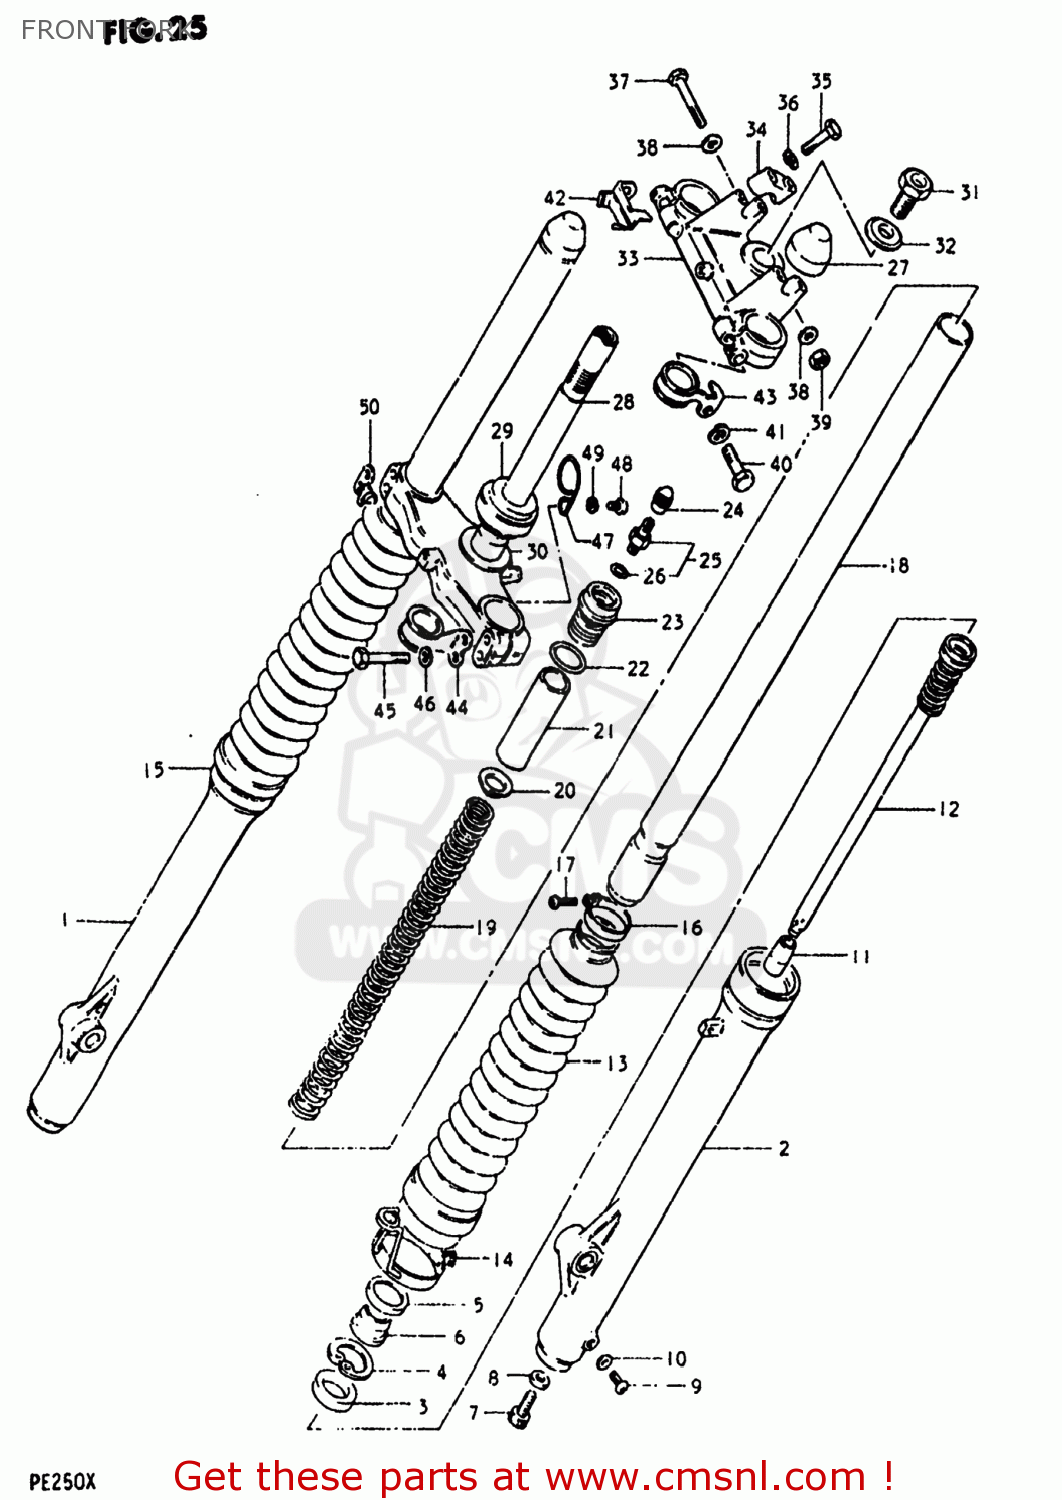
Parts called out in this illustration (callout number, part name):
1	TUBE,OUTER,RIGHT
2	TUBE,OUTER,LEFT
3	OIL SEAL,FRONT FORK
4	5
5	CASE,DUST SEAL
6	SEAL,DUST
7	BOLT,FORK CYLINDER(10X25)
8	GASKET (NAS)
9	SCREW
10	GASKET,DRAIN,PLUG (NAS)
11	PIECE,OIL LOCK
12	CYLINDER,FRONT FORK
13	BOOT
14	BAND,FORK COVER BOOT
15	BAND,FRONT FORK COVER
16	BAND,BOOT
17	SCREW
18	TUBE,FORK,INNER
19	SPRING
20	GUIDE,FRONT FORK SPRING C
21	COLLAR,SPRING
22	O RING
23	CAP,FORK INNER TUBE
24	CAP,VALVE
25	VALVE
26	O RING
27	CAP
28	STEM,STEERING
29	BEARING
30	WASHER,THRUST
31	BOLT
32	WASHER
33	HEAD,STEERING STEM
34	HOLDER,HANDLEBAR
35	BOLT
36	LOCK WASHER
37	BOLT 8X50
38	WASHER
39	NUT
40	BOLT
41	LOCK WASHER
42	BRACKET,TOOL FITTING,UPPER
43	GUIDE,CABLE
44	CLIP,CABLE
45	BOLT 8X45
46	LOCK WASHER
47	CLIP
48	SCREW
49	LOCK WASHER
50	BRACKET,TOOL FITTING,LOWER
